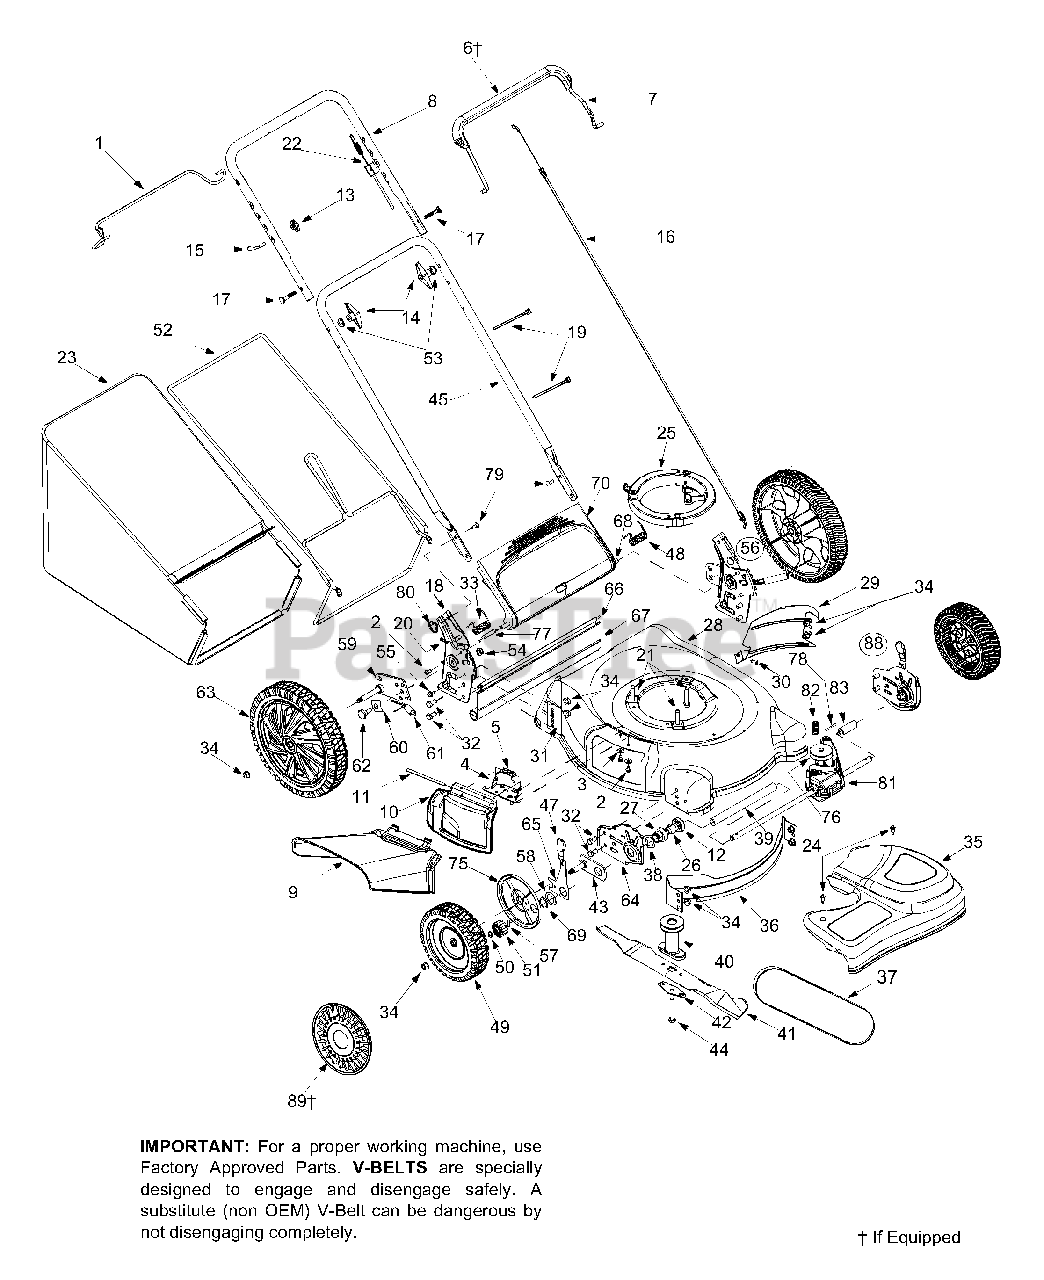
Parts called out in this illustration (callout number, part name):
1	Lower Bail Handle
2	TT Screw 1/4-20 x 0.5
3	Bell Washer.265 x 0.75
4	Deflector Chute Adapter
5	Torsion Spring
6	Deluxe Bail Cover If Equipped
9	Chute Deflector
10	Mulch Plug Complete
11	Hinge Pin
12	Bearing Retainer
13	Handle Knob
14	Handle Knob
15	Eye Bolt
16	Control Cable - 37.75"
16	Control Cable - 40.75"
16	Control Cable - 58.25"
17	Carriage Bolt 5/16-18 x 2.0
18	RH Handle Bracket
18	LH Handle Bracket
19	Cable Tie
20	Cotter Pin
21	Self-Tapping Sems Screw
22	Drive Cable - 50.50"
23	Grassbag Assembly
24	Shoulder Screw # 12 -24
25	Engine Spacer
26	Bearing Sleeve
27	Bearing Support
30	Screw AB: 1/4-14:.625
32	Hex Screw 3/8-16 x.75
33	Torsion Spring RH
34	Flange Lock Nut 3/8-16
35	Transmission Cover (Gray)
38	Wave Washer
39	Sleeve Spacer 9.04" Lg.
40	Blade Adapter w/ Pulley
41	21" Mulching Blade
42	Blade Bell Support
43	Pivot Plate Assembly
44	Hex Screw 3/8-24 x 2.50
47	Adjustment Knob
48	Torsion Spring LH
49	Wheel 8 x 2.125
50	Snap Ring
51	Gear 14T RH FWD
53	Saddle Washer
54	Hex Flange Lock Nut 3/8-16
55	TT Scr. w/Washer 1/4-20 x.625
56	RH Handle Bracket Assembly
56	LH Handle Bracket Assembly
57	Dowel Pin
58	Washer
59	Pivot Arm Assembly - RH
59	Pivot Arm Assembly - LH
60	Rear Spring Lever
61	Foam Grip
62	Shoulder Scr.500 Dia. x.434
63	Wheel, 12 x 2.125
66	Wire
67	Rear Trailing Shield
68	Pivot Rod
69	Snap Ring
70	Rear Discharge Door
75	Wheel Dust Cap
76	Input Pulley
77	Spacer.375 x.50 x 1.02" Lg.
78	Roll Pin
79	Carriage Bolt 1/4-20
80	Wing Nut
81	Transmission Assembly
82	Belt Tension Spring
83	Slev. Spacer 2.1" Lg.
88	Height Adjustment Assembly RH
89	Hub Cap If Equipped
